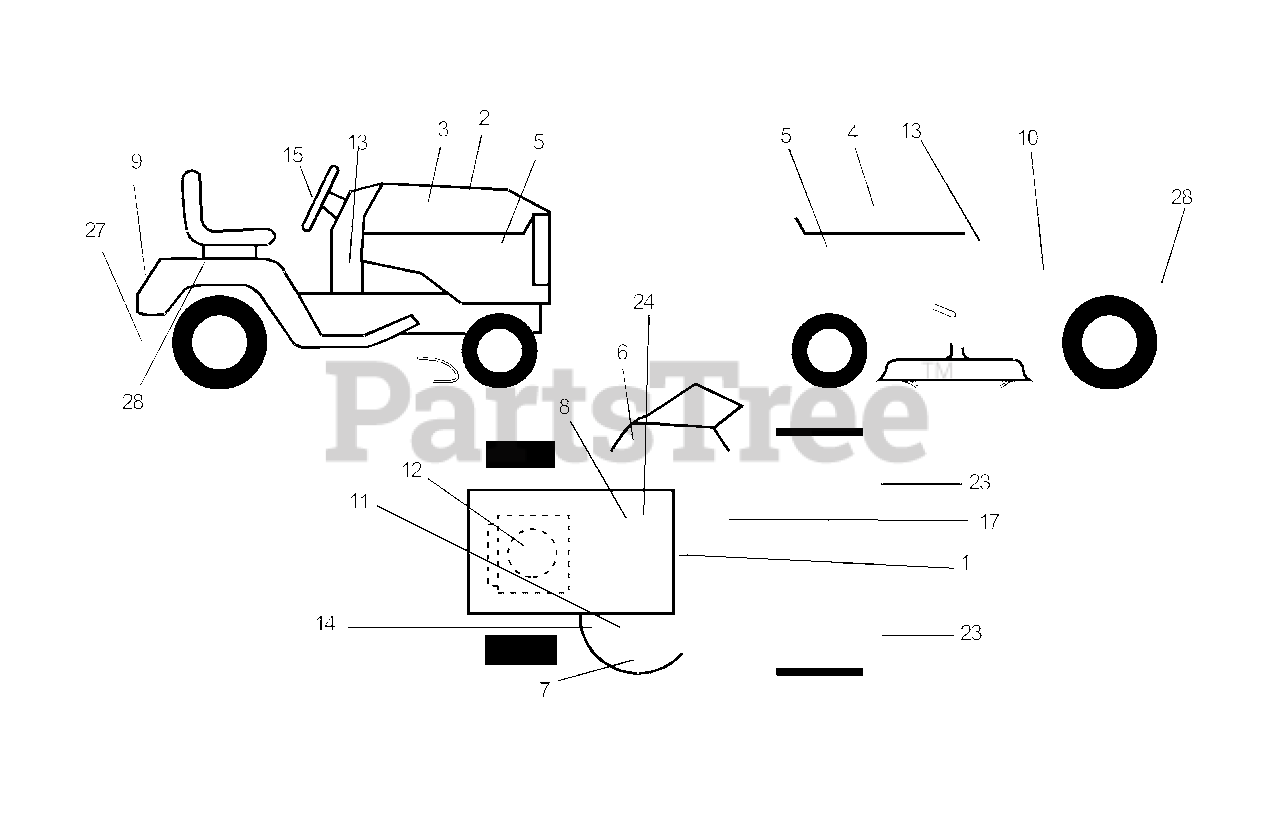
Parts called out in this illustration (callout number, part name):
1	Decal, Operating Instruction
2	Decal, Replt
3	Decal, Hood, RH
4	Decal, Hood, LH
5	Decal, Side Pnl
6	Decal, Warning
7	Decal, Deck Mul
8	Decal, Batt Power Pro
9	Decal, Fender
10	Decal, Danger
11	Decal, Clutch/Brake
12	Decal, Engine
13	Decal, Dash Panel
14	Decal, V-Belt Schematic
15	Decal, Ins. Whl. Strg.
17	Decal, Saddle Brake Parking
23	Reflector, Taillight
24	Decal, Btry Dngr/Psn
27	Decal,Drawbar
28	Decal, Fender Auto
